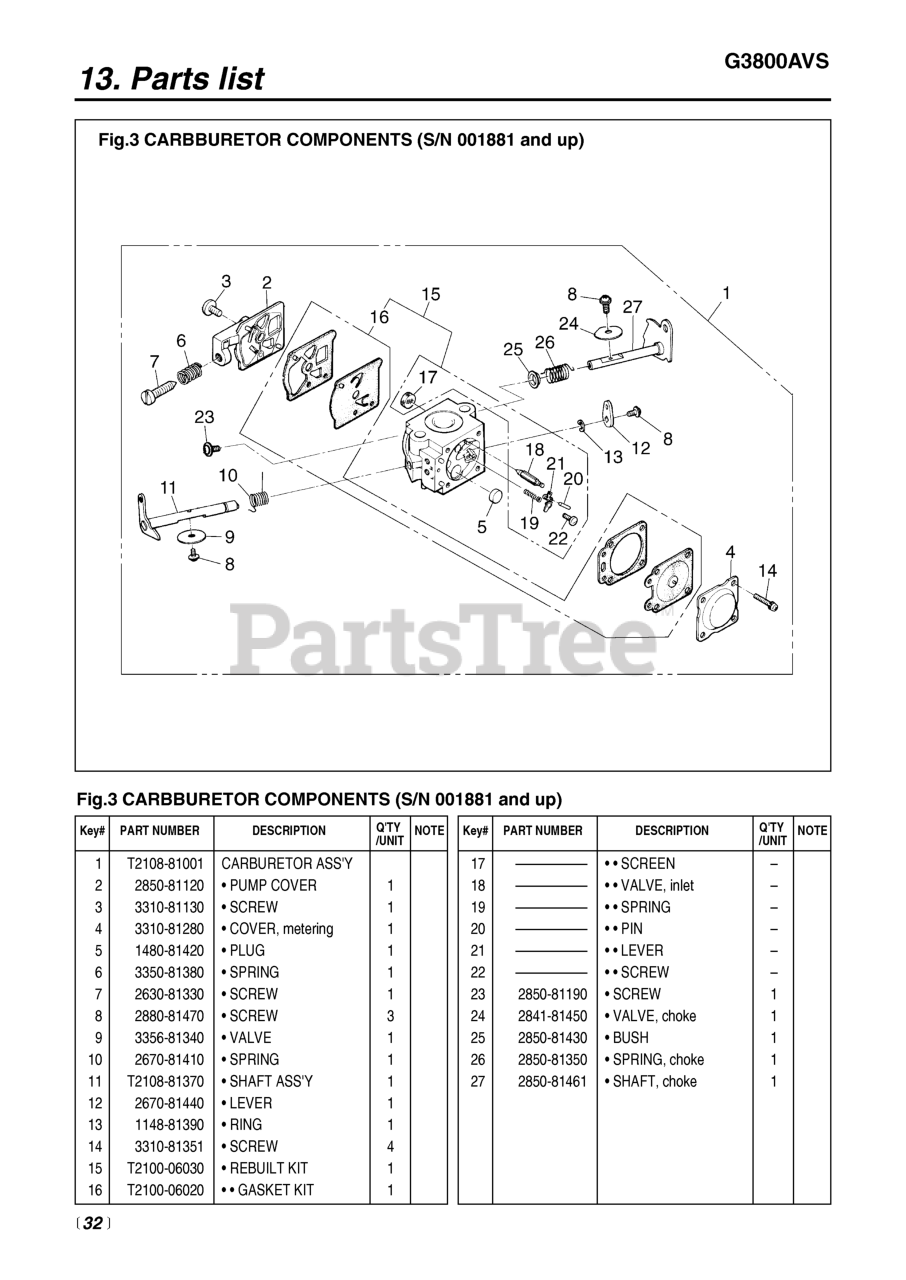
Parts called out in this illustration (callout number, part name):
1	CARBURETOR ASSY.
2	COVER, PUMP
5	PLUG, WELSH
6	SPRING, IDLE
8	SCREW (RPLS 3310-81360)
9	VALVE, THROTTLE
10	SPRING, RETURN
11	SHAFT ASSEMBLY, THROTTLE
12	VALVE, THROTTLE
14	SCREW ASSEMBLY
15	REBUILD KIT
16	KIT, GASKET (G3800AVS)
17	SCREEN
18	VALVE
19	SPRING
20	PIN
21	LEVER
22	SCREW
26	SPRING, CHOKE
27	SHAFT, CHOKE
